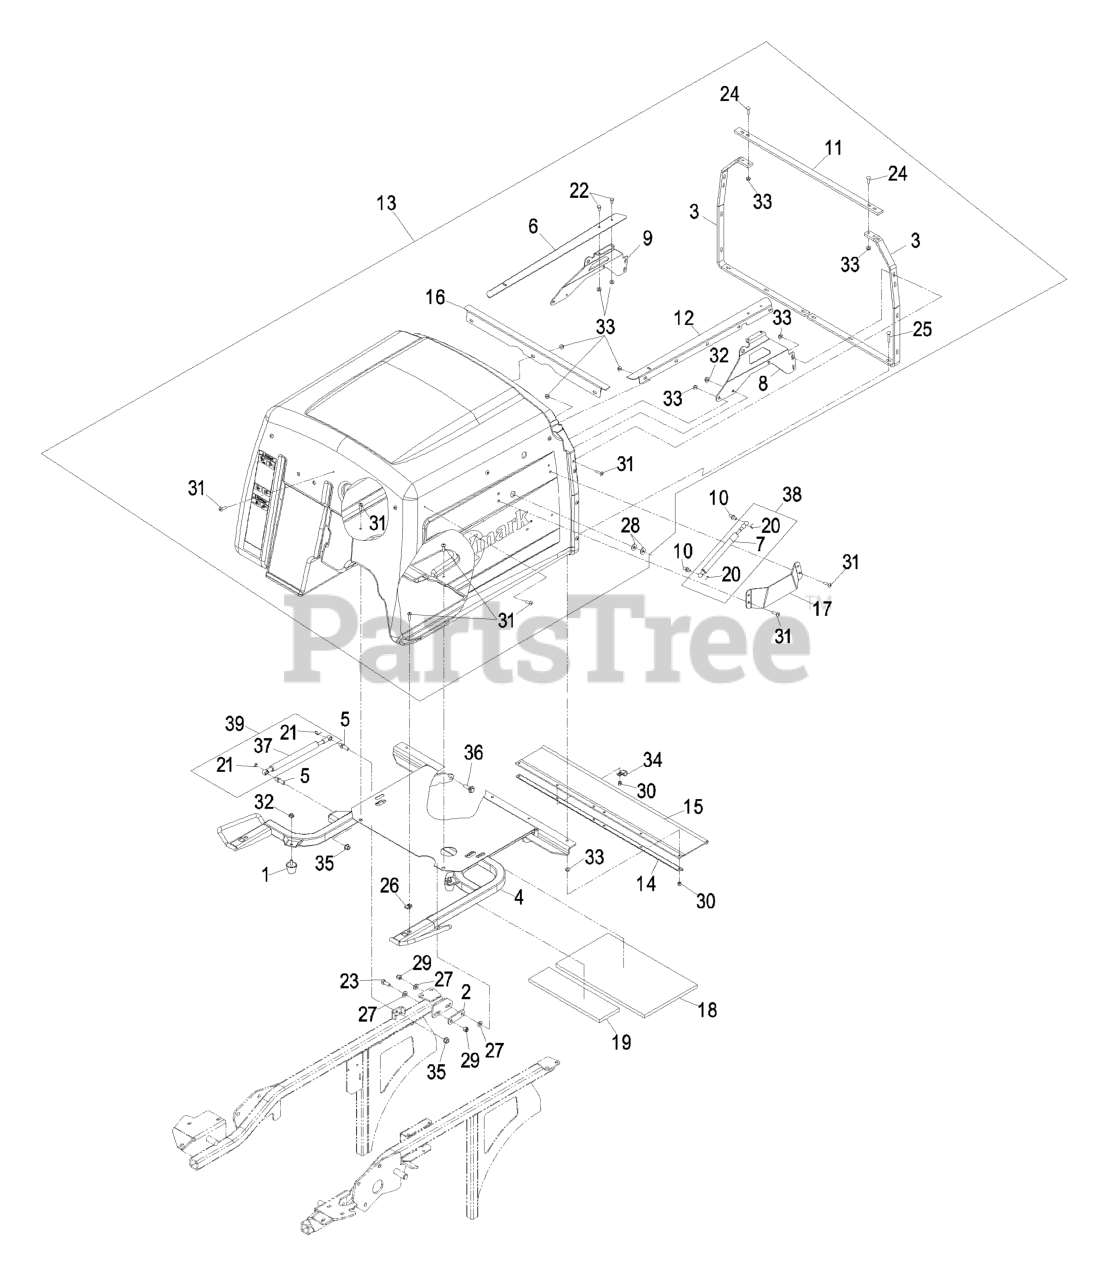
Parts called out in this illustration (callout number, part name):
1	BUMPER-RUBBER
2	ARM-LIFT, DECK
3	REINFORCEMENT-HOPPER
4	HOPPER FRAME ASM
5	STUD-BALL
6	ANGLE-SCREEN TRACK, RH
7	SHOCK-GAS TENSION
8	BRACE-DOOR PIVOT, LH
9	BRACE-DOOR PIVOT, RH
10	STUD-BALL
11	BRACKET-FRAME CONNECT
12	ANGLE-SCREEN TRACK, LH
13	ASM,HOPPER
14	CHANNEL-FRAME, HOPPER
15	DEFLECTOR-GRASS
16	CHANNEL-SCREEN, FRONT
17	PLATE-GUARD
18	INSULATION-FOAM PAD, REAR
19	INSULATION-FOAM PAD, FRON
20	CLIP-RETAINER
21	CLIP-RETAINER
22	SCREW-HH
23	SCREW-HH
24	SCREW-CARR
25	SCREW-CARR
26	Nut, Retainer
27	WASHER-FLAT
28	WASHER-FLAT
29	NUT-LOCK, NI
30	NUT-LOCK, NI
31	SCREW-TTH
34	CLIP-LOOM
36	SCREW-SHOULDER, HWH
37	SHOCK-COMPRESSION, GAS
38	DAMPER KIT
39	DAMPER KIT
